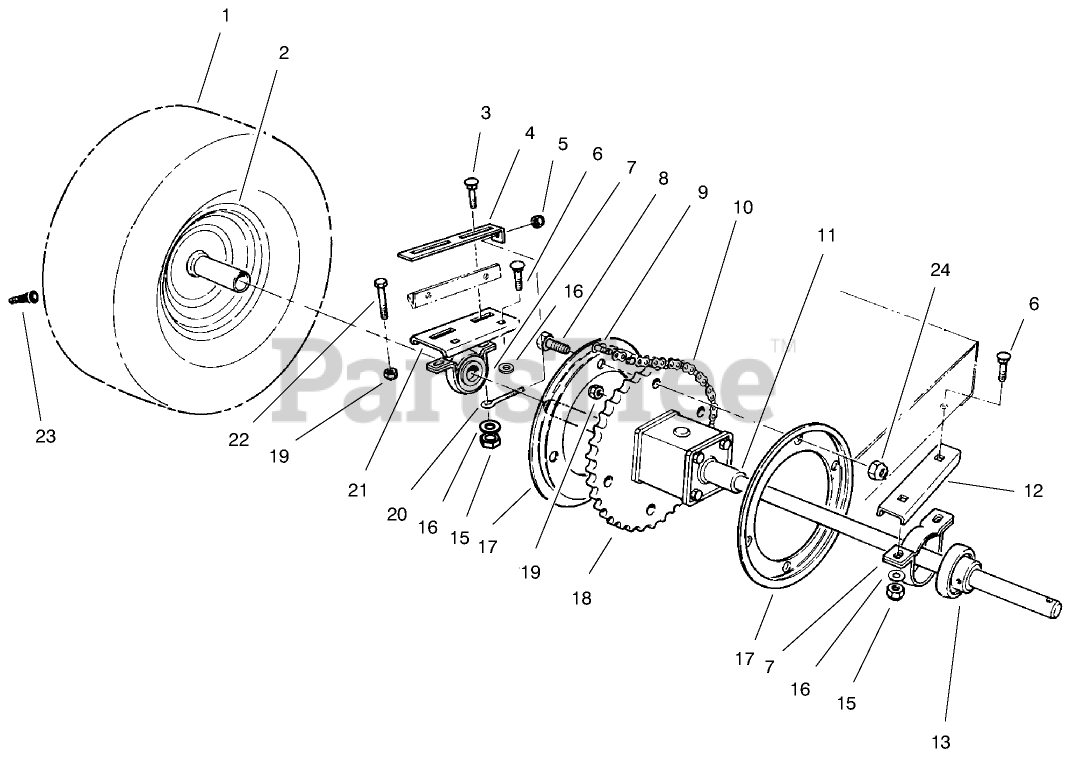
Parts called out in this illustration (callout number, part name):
1	NUT-LOCK, NI
2	THRUST WASHER
3	BEARING-NEEDLE
4	NUT-LOCK, NI
5	SCREW-HH
6	Spindle R.H.
7	Axle (Incl. Ref. #10 & 11)
8	NUT-LOCK, NI
9	WASHER-THRUST
10	BUSHING
11	FITTING-GREASE
12	Pin-RearAxle
13	WASHER-LOCK
14	SCREW-HH
15	WASHER-FLAT
16	RING-RETAINING
17	WASHER
18	WASHER-THRUST
19	Spindle L.H.
21	TIRE 4 PLY
22	Wheel (Incl. Ref. #23)
23	BEARING-CUP, TAPERED
24	NUT-HEX, SLOTTED
25	PIN-COTTER
26	CAP-DUST
27	WASHER-FLAT
28	BEARING-CONE, TAPERED
29	VALVE STEM AND CAP ASM
30	Steering Plate (Incl. Ref. #10 & 11)
31	NUT-SLOTTED
32	PIN-COTTER
33	PIN-COTTER
34	STRG TIE ROD R
35	NUT-HJ (LH THREAD)
36	Socket Assembly L.H. (Incl. Ref. #31)
37	NUT-JAM
38	Socket Assembly R.H. (Incl. Ref. #31)
39	REAR STRG TUBE PP
40	PIVOT ARM WA
41	Pivot Mount (Incl. Ref. #3 & 11)
